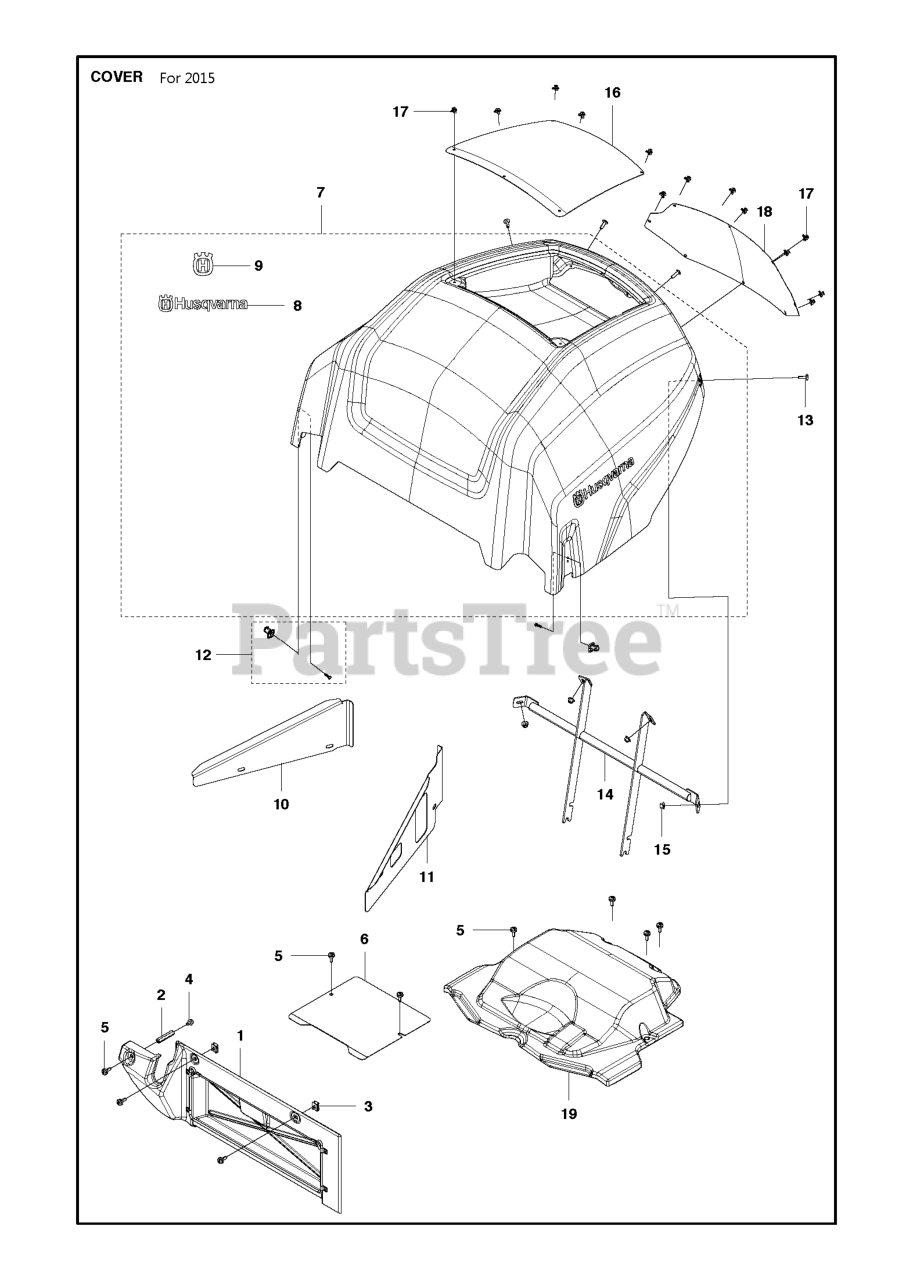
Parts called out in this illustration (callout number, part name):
8	DECAL.HUSQVARNA.210MM
9	DECAL HUSQVARNA CROWN HEIGHT 5
15	NUT FLANGE
